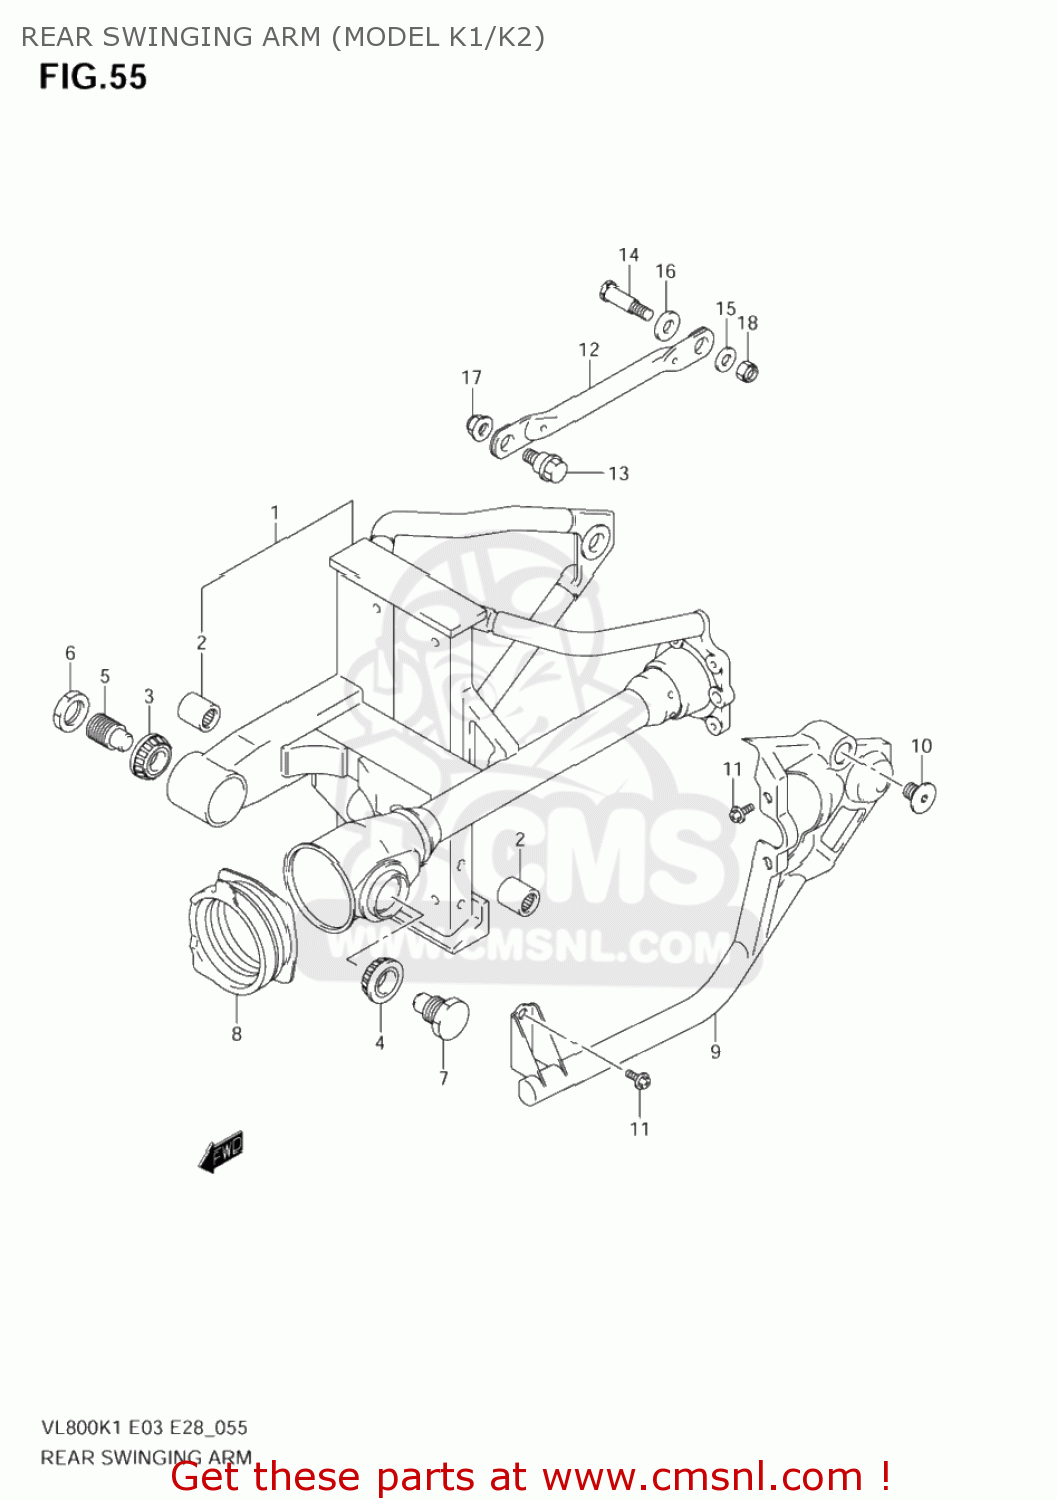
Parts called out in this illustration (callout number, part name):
1	SWINGINGARM SET,RR
2	BEARING(17X24X25)
3	BEARING(17X40X13.25)
4	BEARING(17X40X13.25)
5	BOLT,RR SWGARM PIVOT
6	NUT
7	BOLT,SWINGINGARM PIVOT,L
8	BOOT,PROPELLER SHAFT
9	COVER,RR SWINGINGARM,L
10	BOLT,RR SWGARM
11	BOLT(6X14.1)
12	TORQUE LINK,RR
13	BOLT(10X22)
14	BOLT(10X41)
15	WASHER (10X20X2.3)
16	CUSHION
17	NUT
18	NUT
